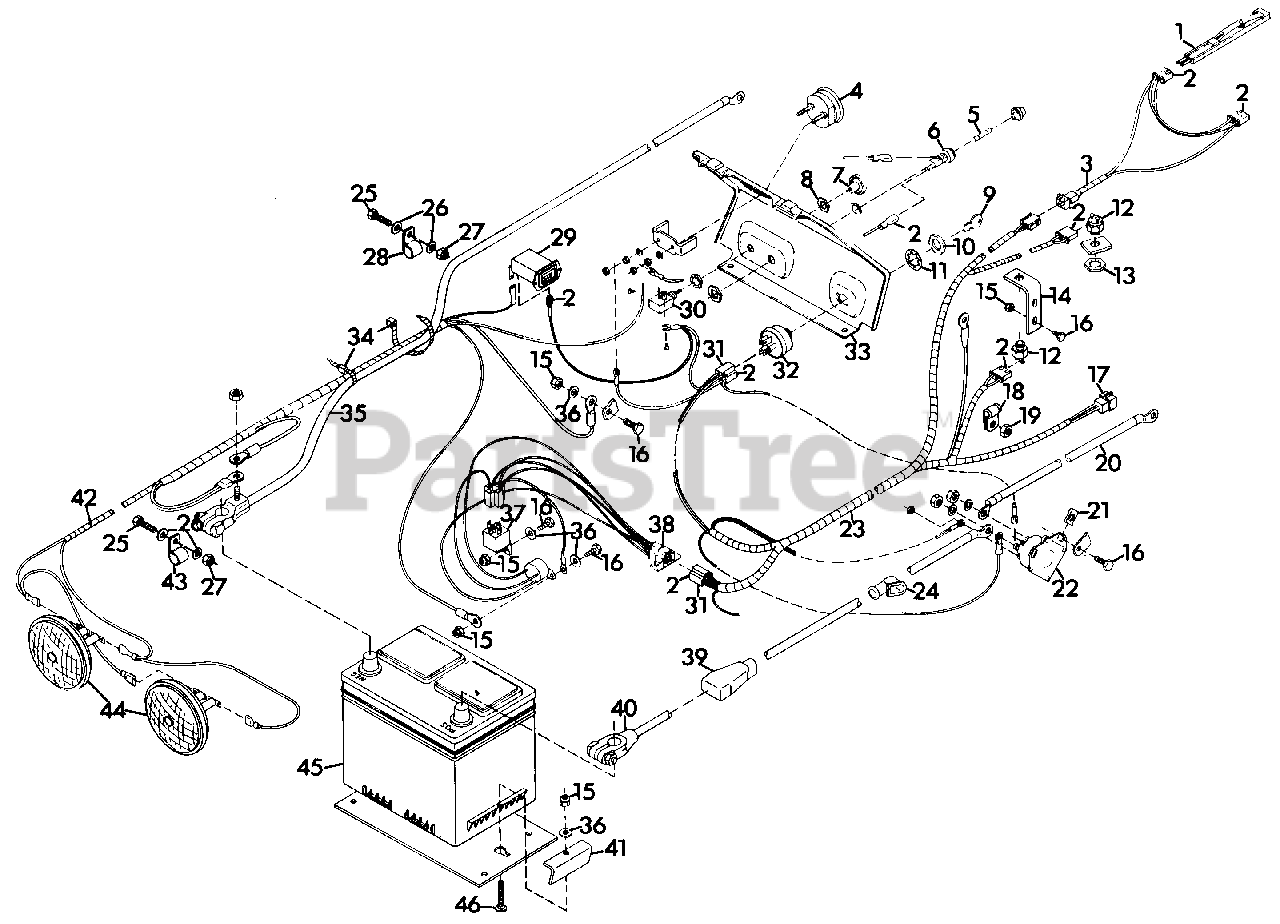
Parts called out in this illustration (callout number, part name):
1	SWITCH, SEAT
2	TERMINAL
3	HARNESS, WIRING SEAT SWITCH
4	GAUGE, AMMETER
5	FUSE, 30 AMP AGC-30
6	FUSE, PANEL
7	KNOB, LIGHT SWITCH
8	NUT, SPECIAL LIGHT SWITCH
9	KEY, IGNITION SWITCH
10	NUT, JAM 9/16-24
11	WASHER, LOCK 9/16 INT. TOOTH
12	SWITCH, INTERLOCK
13	NUT, STAMPED 9/16-18
14	BRACKET, SWITCH
15	NUT, LOCK 1/4-20
16	BOLT, HEX 1/4-20X.75
17	CONNECTOR
18	CLAMP
19	NUT, LOCK 3/8-16
20	CABLE, STARTER
21	NUT, SPEED 1/4-20
22	SWITCH, MAGNETIC
23	HARNESS, WIRING
24	BOOT, BATTERY CABLE
25	BOLT, HEX 5/16-18X1.00
26	WASHER, FLAT .344X.688X.065
27	NUT, LOCK 5/16-18
28	CLAMP, NYLON
29	HOURMETER
30	SWITCH, LIGHT
31	CONNECTOR
32	SWITCH, IGNITION
33	PANEL, INSTRUMENT
34	TIE, CABLE
35	CABLE, NEGATIVE BATTERY
36	WASHER, FLAT .281X.625X.065
37	RELAY
38	MODULE, TIME DELAY
39	COVER, BATTERY TERMINAL
40	CABLE, BATTERY TO MAGNETIC SWITCH
41	CLAMP
42	HARNESS, WIRING GROUND AND LIGHTS
43	CLAMP, NYLON
44	HEADLIGHT
45	BATTERY, 12 VOLT
46	BOLT, 1/4-20X1.75 RD HD SQ NK
